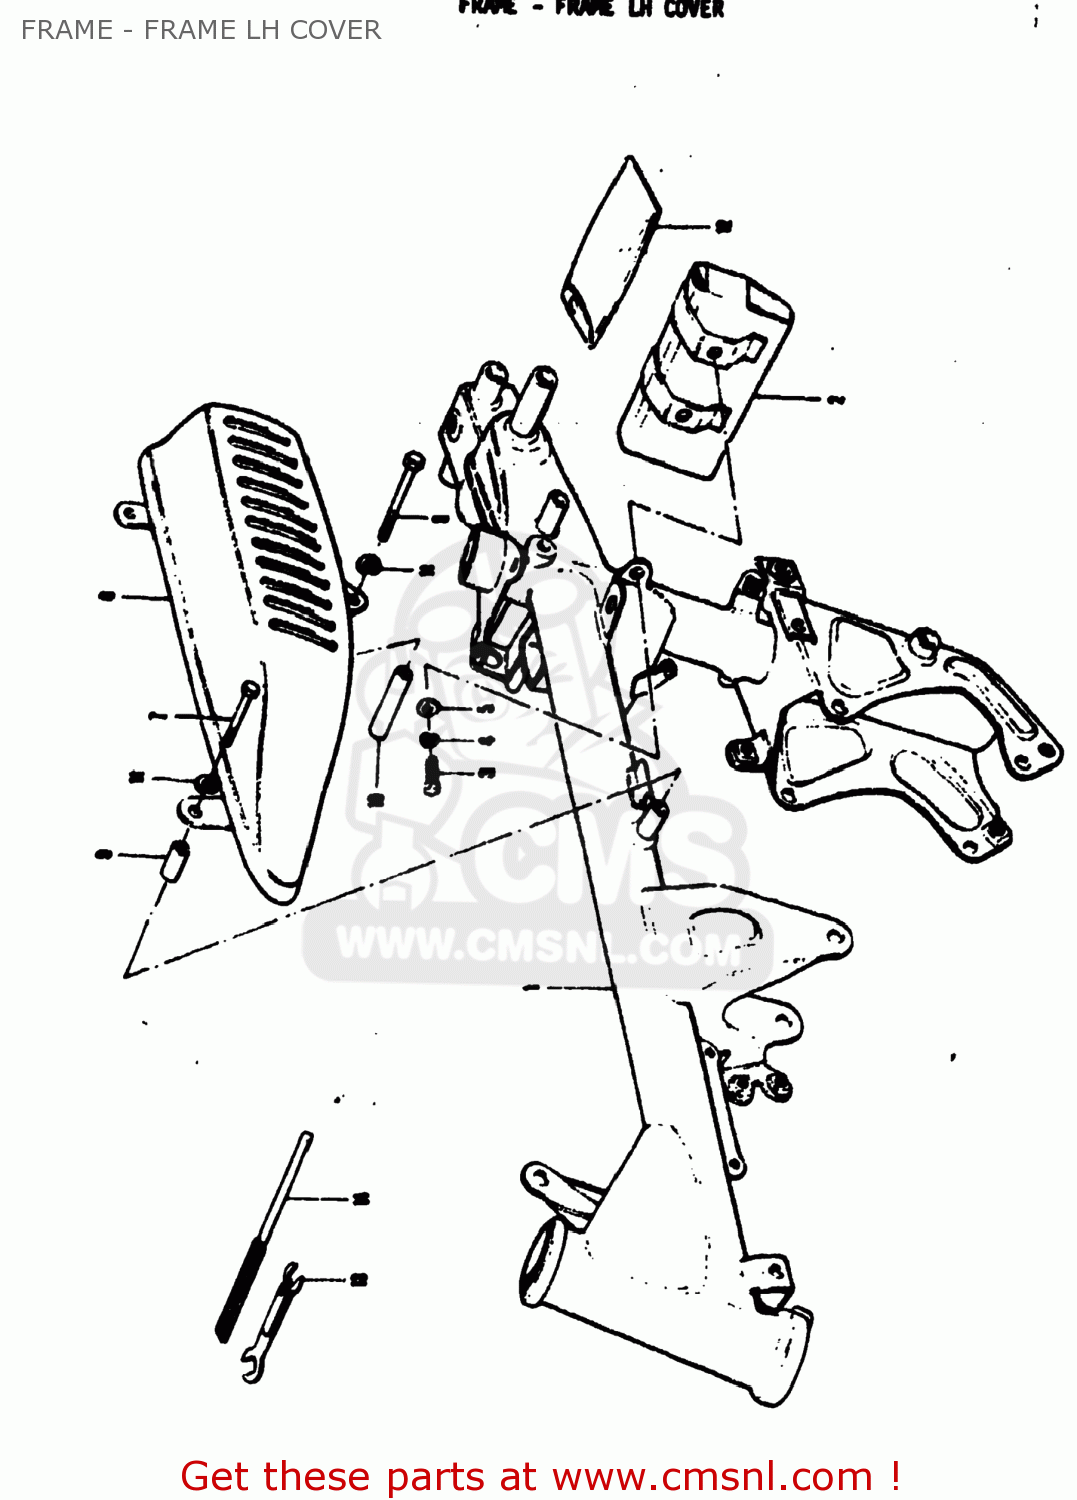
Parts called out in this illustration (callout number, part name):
3	BOLT
4	LOCK WASHER
5	WASHER
7	BOLT
8	BOLT(6X70)
9	SPACER (6.8X10X27.4)
10	SPACER
11	LOCK WASHER
12	TOOL ASSY
13	WRENCH, CONTACT POINT
14	CONTACT POINT FILE
